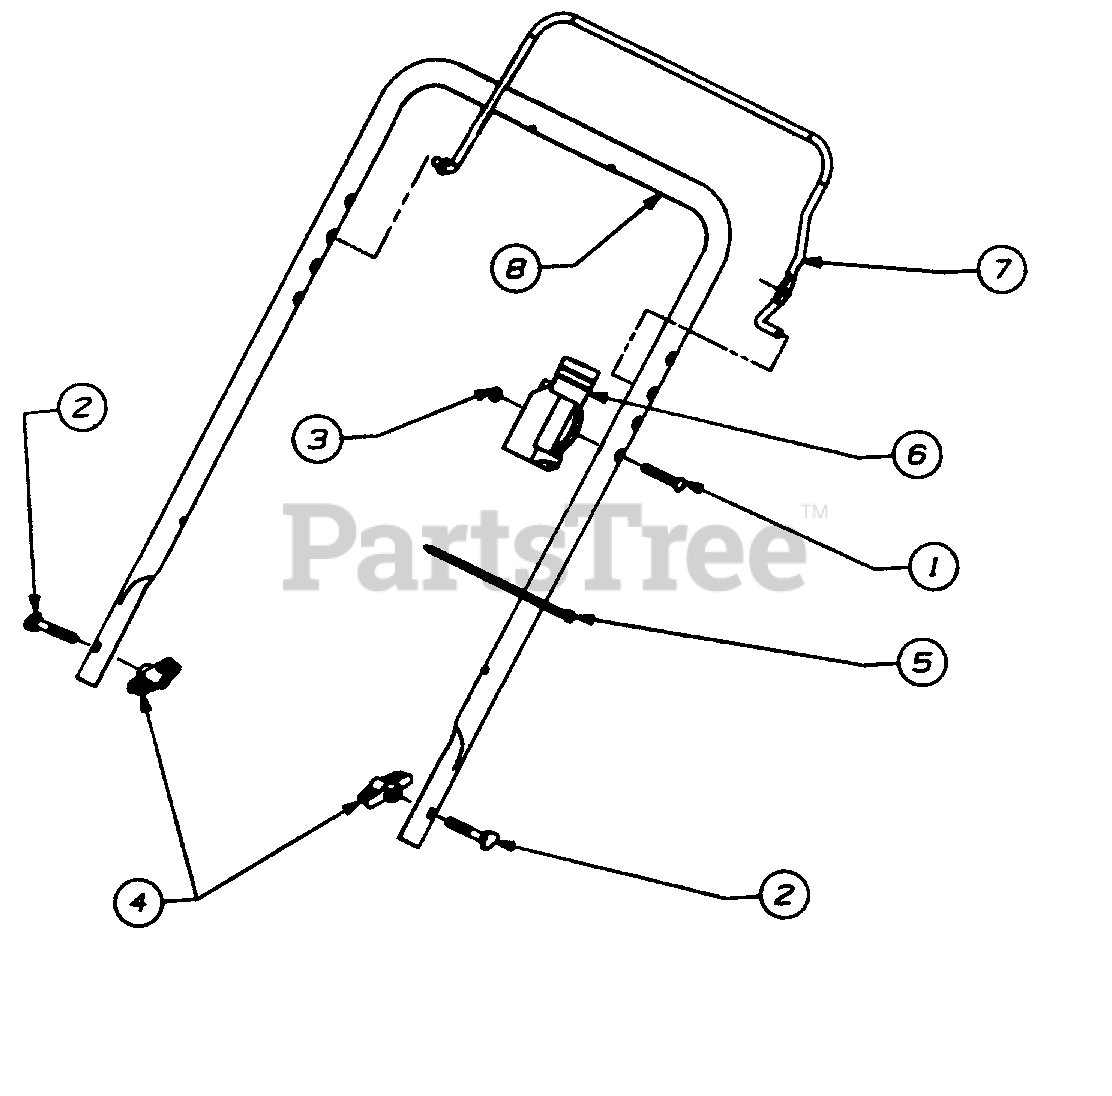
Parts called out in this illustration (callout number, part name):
1	Screw-Oval C-Sink L
2	Bolt Carriage
3	Nut Insl. Lock
4	Knob-Handle
5	Tie Cable
6	Body-Lever Control
7	Handle Ass'y. Control
